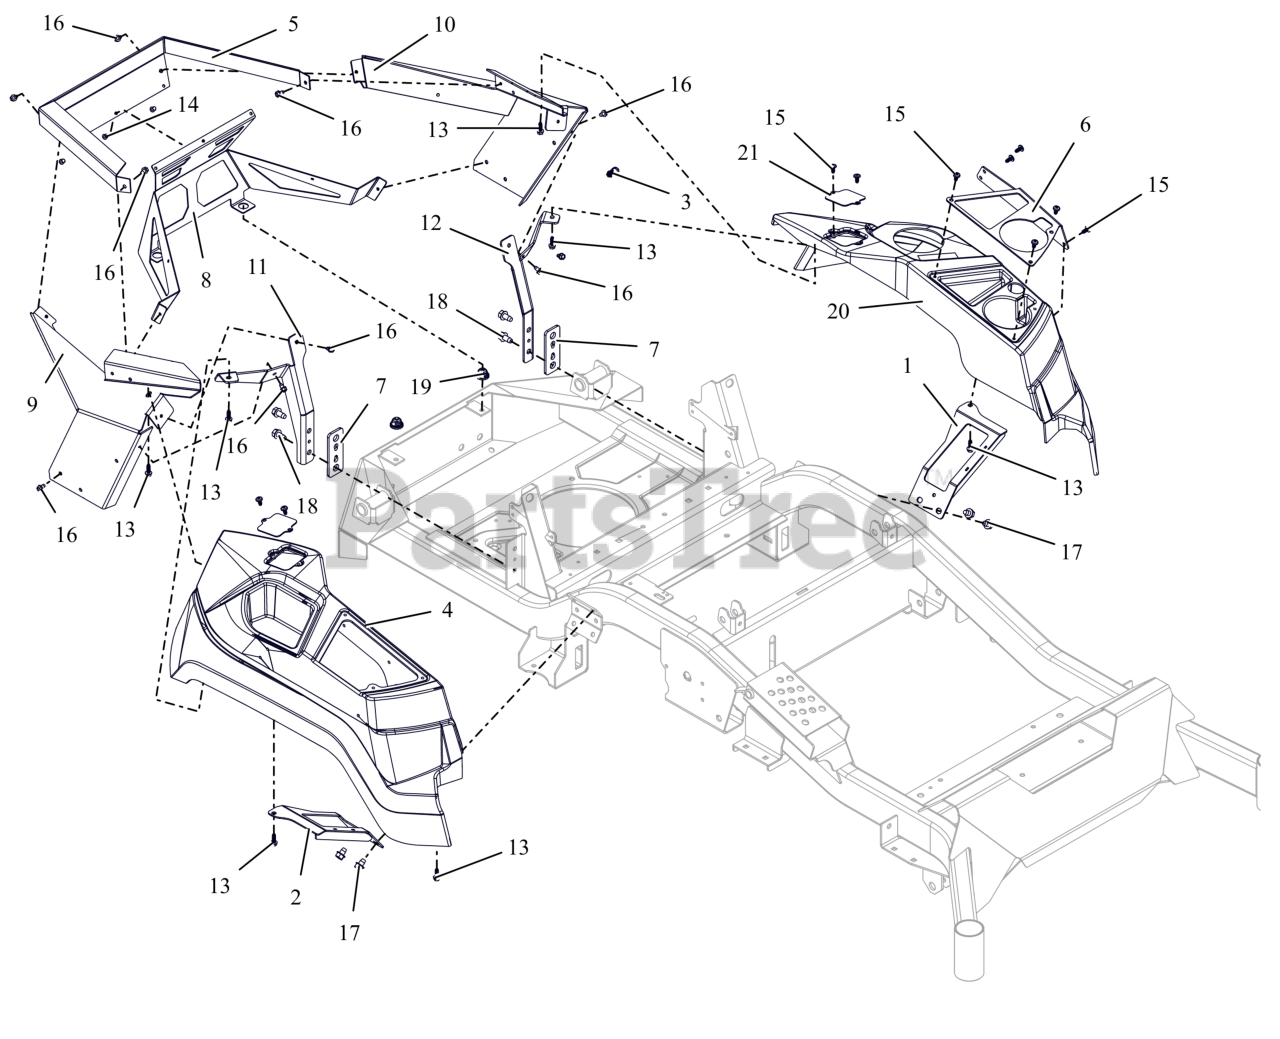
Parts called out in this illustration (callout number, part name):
1	WLDMT, LH FENDER MOUNT
2	WLDMT, RH FENDER MOUNT
3	CLIP, CABLE GUIDE
4	FENDER, RH APEX - 2017
5	GUARD,ENGINE WRAP
6	PLATE, APEX CUP HOLDER COVER
7	PLATE, CONTROL PANEL SPACER
8	GUARD, ENGINE
9	PANEL, RH REAR FENDER MOUNT
10	PANEL, LH REAR FENDER MOUNT
11	BRKT, RH FENDER MTG (ORANGE)
12	BRKT, LH FENDER MOUNT (ORANGE)
13	SCR, PLASTITE .25-10X.75 ZCC
14	RIVET, .1875 AL/AL .126-.250
15	SCR-PAN .25-15X.50 6L H/LZB500
16	SCR,TAP .25-20X.375 HWH TR ZCC
17	SCR,TAP .375-16X.50 HWH TR ZCC
18	SCR,TAP .375-16X.75 HWH TR ZCC
19	GROMMET, 10MM BOLLHOFF
20	FENDER, LH APEX
21	PLATE, ROPS HOLE-HD
